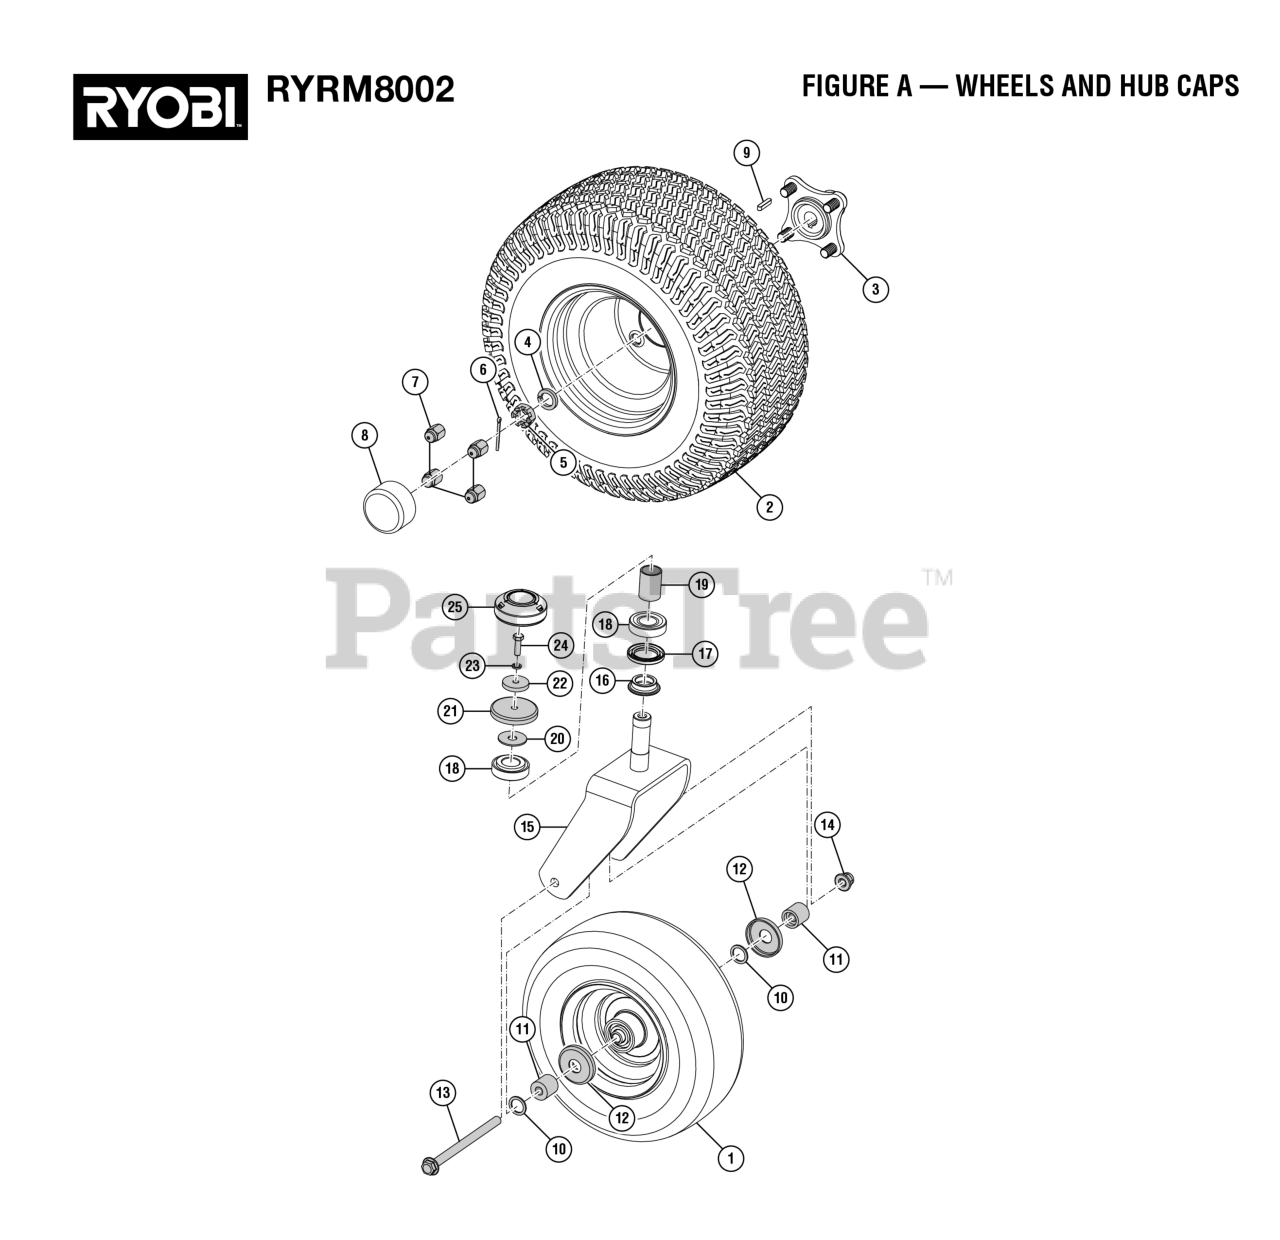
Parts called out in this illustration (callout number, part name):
1	Front Wheel Assembly
2	Rear Wheel Assembly
3	Wheel Hub
4	Lock Spring Washer (20.6 x 30.6 x 4.8t)
5	Castle Nut (M20)
6	Drive Shaft Cotter Pin
7	Acorn Nut (M14)
8	Wheel Hub Cover
9	Key (6 mm x 6 mm x 30 mm)
10	Washer (OD28 x ID20.5 x 2t)
11	Caster Wheel Spacer
12	Front Wheel Bearing Cover
13	Flange Bolt (M12 x 170 mm, Hex Hd.)
14	Flange Nut (M12)
15	Caster Fork
16	Bearing Assembly Base
17	Rubber Seal
18	Roller Bearing (ID 25 mm x OD 52 mm)
19	Bearing Assembly Spacer
20	Fender Washer (OD40 x ID12.5 x 2t)
21	Bearing Assembly Cap
22	Fender Washer (OD37 x ID8.4 x 6t)
23	Lock Washer (OD9.8 x ID8.5 x 5t)
24	Bolt (M8 x 25 mm, Hex Hd.)
25	Caster Fork Cover
